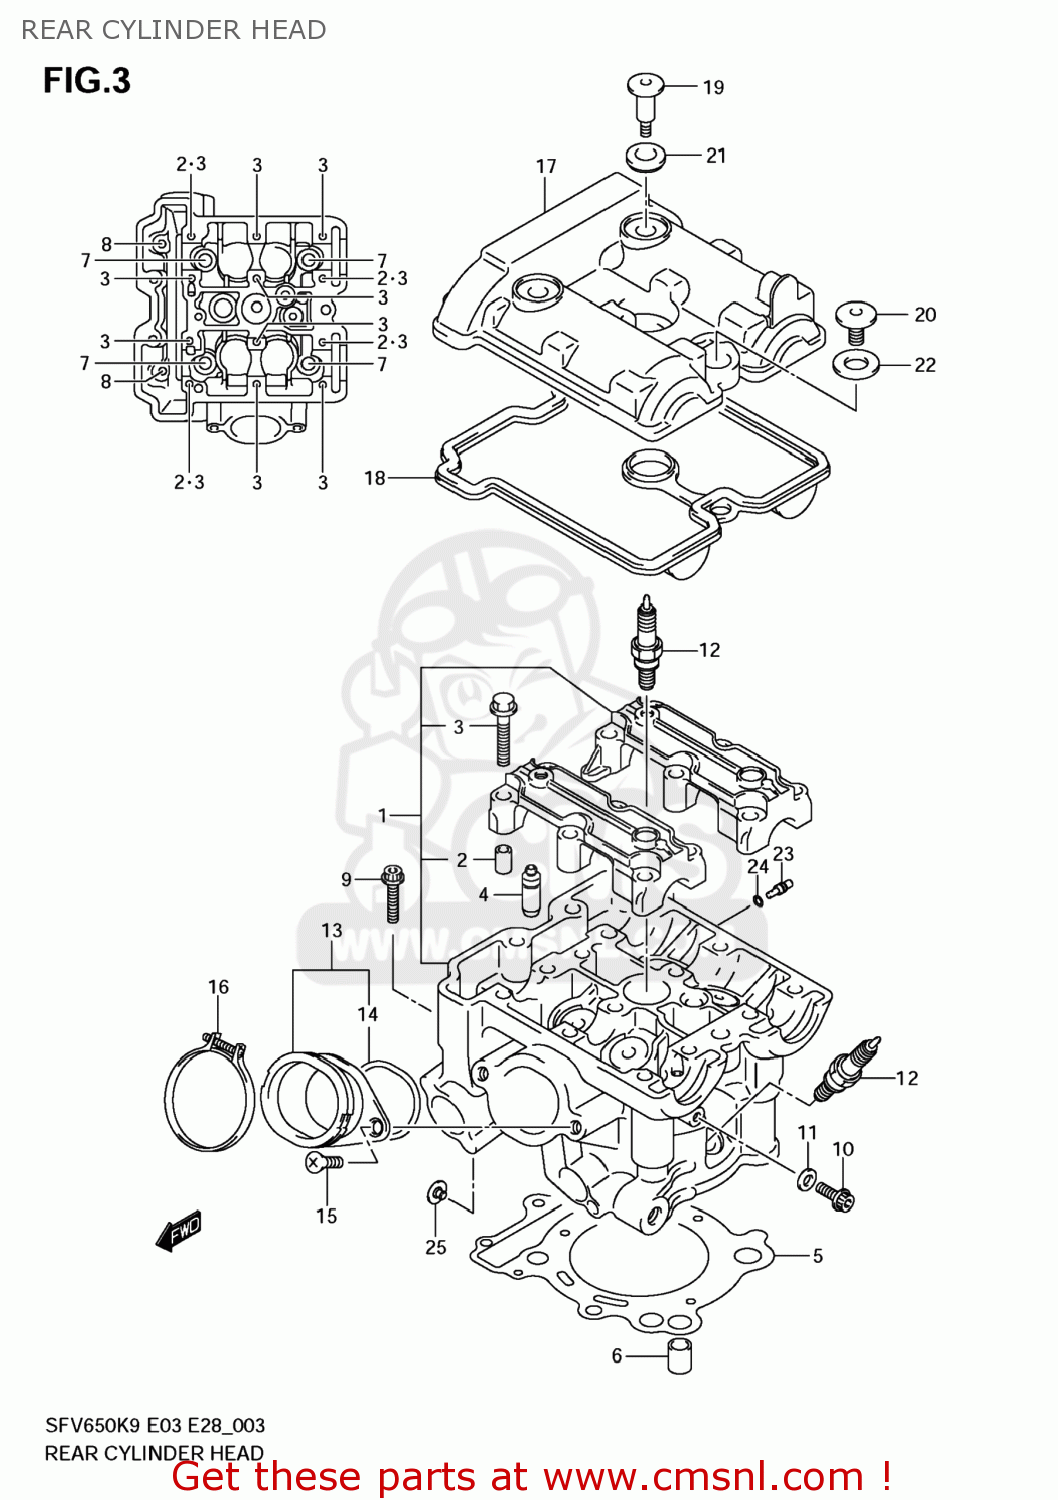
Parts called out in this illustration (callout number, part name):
1	HEAD ASSY,CYLI
2	PIN(6.2X8X11)
3	BOLT(6X39)
4	GUIDE,VALVE
5	GASKET,CYLINDER HEAD (NAS)
6	PIN
7	BOLT,CYLINDER HEAD(L:160)
8	BOLT(6X70)
9	BOLT
10	BOLT
11	GASKET(5.8X13X1.2) (NAS)
12	PLUG,SPARK(IU24D)
13	PIPE ASSY,INTAKE RR
14	O RING(D:2.4,ID:47X42)
15	SCREW
16	CLAMP
17	COVER,CYLINDER HEAD RR
18	GASKET,CYLINDER HEAD COVER (NAS)
19	BOLT(7X17.5)
20	BOLT(7X31)
21	WASHER,CYL HEAD COVER
22	CUSHION,HEAD COVER BOLT
23	JET(8)
24	O RING(D:1.2,ID:4)
25	CAP,ENGINE MOUNTING
